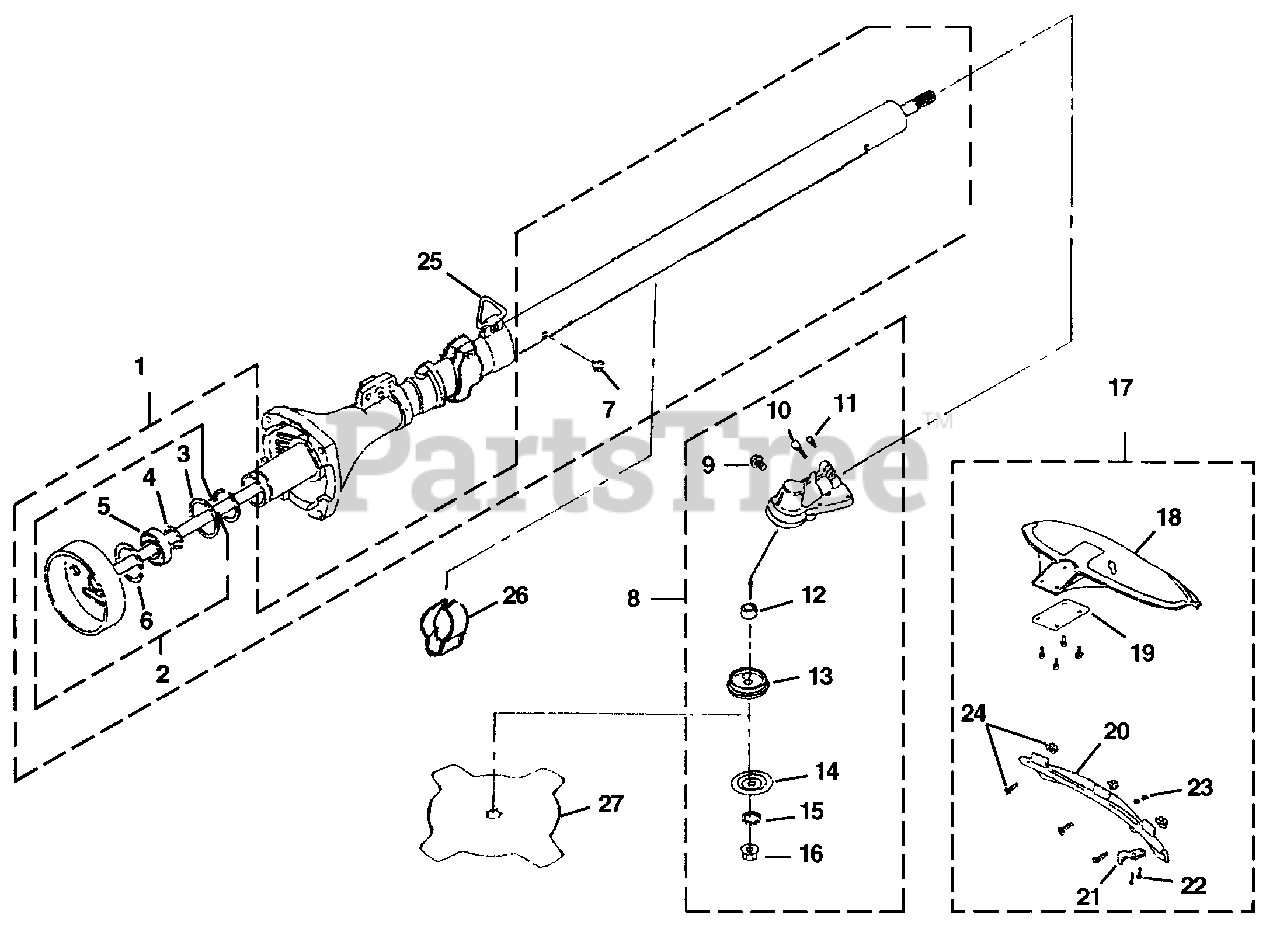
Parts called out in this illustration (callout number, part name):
1	DRIVESHAFT HSG
2	DRIVESHAFT ASSY
4	SNAPRING - Outer
5	BEARING, BALL
6	SNAPRING - Inner
7	BOLT - Oil
8	GEARHEAD ASSEMBLY
9	BOLT - Grease
10	SCREW - Socket Hd (M5 X 15 SW)
11	SCREW - Socket Hd (M6 X 20)
13	WASHER - Flange
14	WASHER - Clamp
15	WASHER - Spring
17	DEFLECTOR ASSY
18	DEFLECTOR - Blade
19	FIXING PLATE
20	DEFLECTOR - Grass
22	BOLT
24	BOLT AND NUT SET
25	HANGER ASSEMBLY
26	CLAMP - Wire
27	BLADE - Cutter
